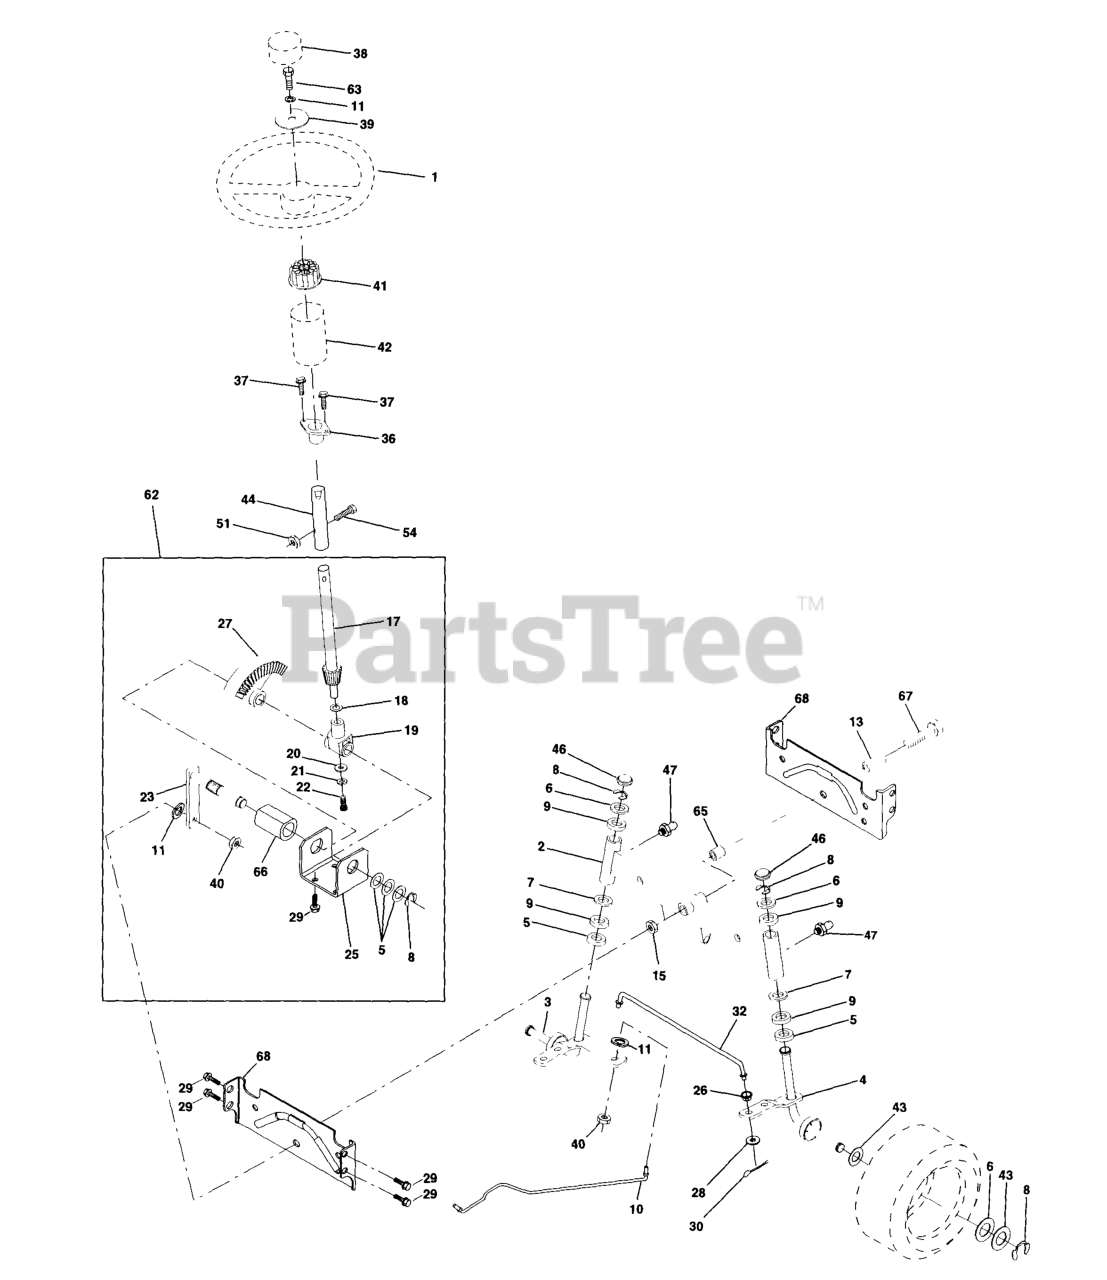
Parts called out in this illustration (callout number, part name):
1	STEERING WHEEL
2	FRONT AXLE ASSY
3	SPINDLE ASS'Y LH
4	SPINDLE ASM RH
5	THRUST WASHER
9	BRNG T
10	LINK.DRAG.DROPPED.LT
11	WASHER, LOCK 3/8
13	BEARING AXLE
15	NUT-LOC,FLANGE LT
17	SHAFT ASM STEERING
18	THRUST WASHER
19	SHAFT,SUPPORT
20	WASHER
21	LOCKWASHER
22	SCREW
23	SHAFT PITMAN
25	BRACKET STEERING
27	GEAR.SECTOR
29	SCREW
32	ROD ASSY/TIE BALL
36	BUSHING, STEERING
37	SCREW.TT.#10-32X.5.3/8.FLANGE
38	INSERT,STR WHEEL
39	WASHER T
40	GRIPCO NUT
41	ADAPTER LT
42	BOOT, STEERING
44	EXT SHAFT STEERING
46	CAP.SPINDLE.BLACK
47	ZERK M
51	NUT.71038.31-18.HEX.NYLOCK
54	BOLT.5/16-18X1-1/4 FULL.THREAD
62	KIT, STEERING ASSEMBLY
63	BOLT
65	SPACER AXLE
66	BEARING ARM
67	Bolt, Fin Hex 5/8-11 UNC x 2-3/4
68	AXLE, BRACE
